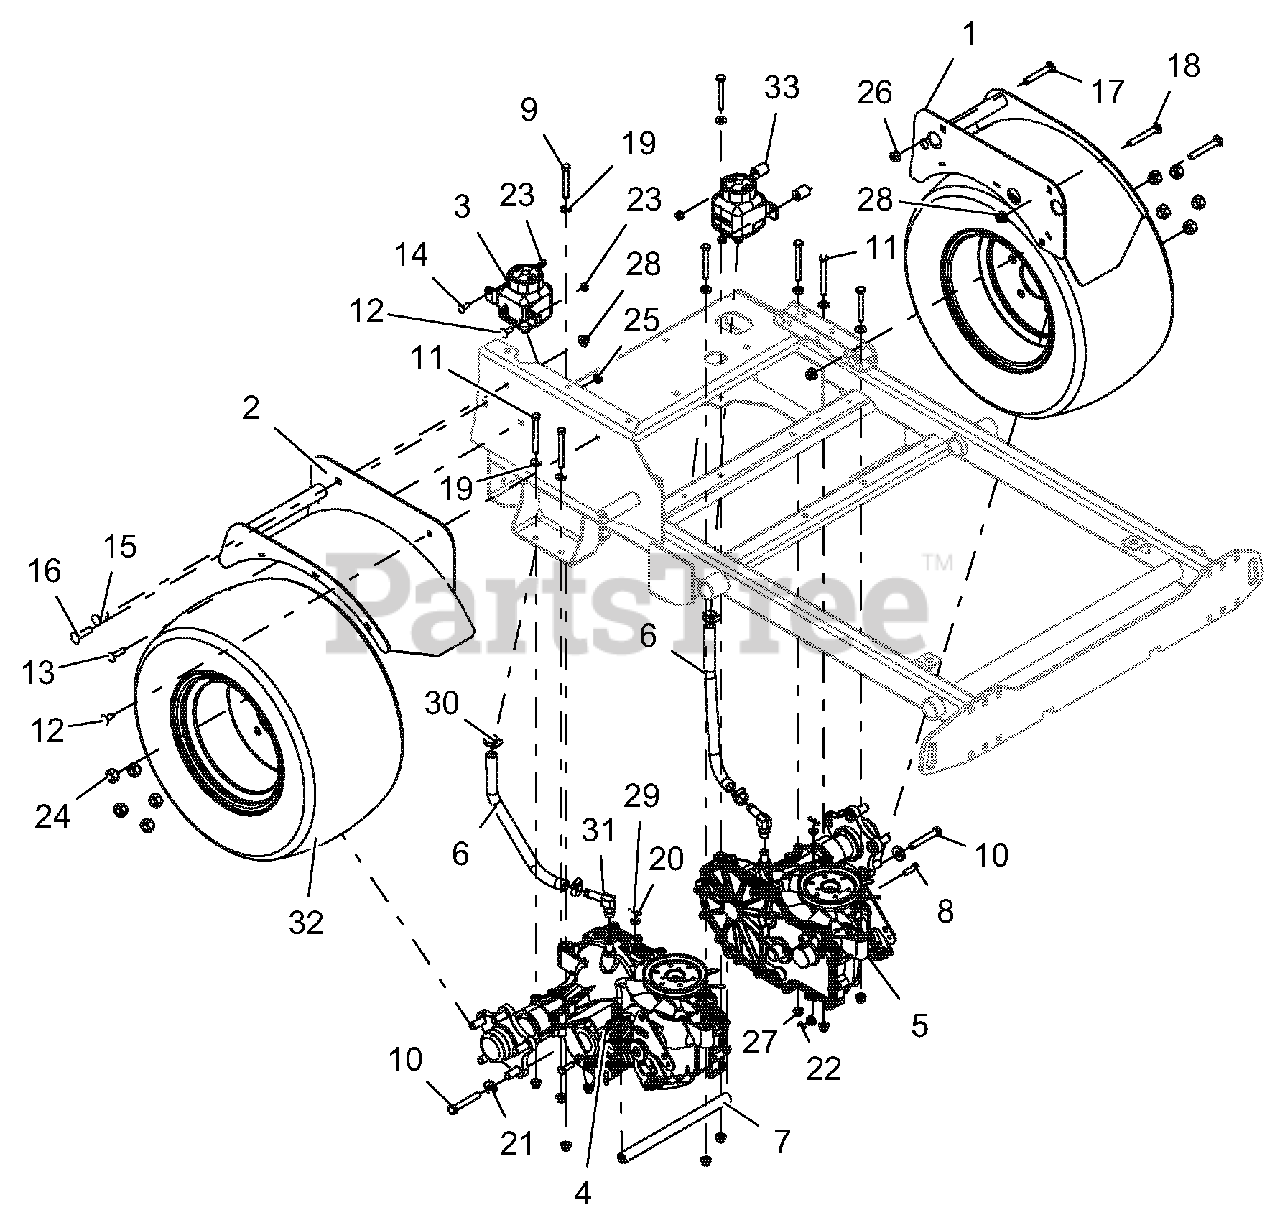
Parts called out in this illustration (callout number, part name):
1	WLDMT, LH FENDER-RED
2	WLDMT, RH FENDER-RED
3	TANK, EXPANSION ZT2800
4	TRANSAXLE, 3400, PRO-STANCE, RH
5	TRANSAXLE, 3400, PRO-STANCE, LH
6	HOSE, HYD OVERFLOW
7	SHAFT, CROSS BRACE
8	BLT-HEX .31-18X1.00 GR5 YWZC
9	BLT-HEX .31-18X2.50 GR5 YWZC
10	BLT-HEX .38-16X2.50 GR5 YWZC
11	BLT-HEX .31-18X3.00 GR5 YWZC
12	BLT-RDHDSQNK .31-18X.75 G5 YWZC
13	BLT-RDHDSQNK .31-18X1.25 G5 Y
14	BLT-RDHDSQNK .25-20X.75 G5 YWZC
15	BLT-RDHDSQNK .38-16X1.00 G5 YWZC
16	BLT-RDHDSQNK .38-16X1.50 G5 Y
17	BLT-RDHDSQNK .38-16X2.50 G5 Y
18	BLT-RDHDSQNK .38-16X2.75 G5 Y
19	WSHR-FL-STL.312X.734X.065 YWZ
20	WSHR-FL-STL.281X.62X.065 YWZC
21	WSHR-FL-STL .406X1.00X.188 YWZC
22	@NUT-LK-CTR-JAM .31-18 YWZC
23	NUT-LK-NYL-FLG .25-20 YWZC
24	NUT, LUG .500-13
25	@NUT-SPNLK-FLG .312-18 YWZC
26	NUT, LK-TOP-FLG .38-16 YWZC
27	NUT-LK-NYL-FLG .31-18 YWZC
28	NUT-LK-NYL-FLG .38-16 YWZC
29	PIN-HAIR, ENDRIES #25 YWZC
30	CLAMP, .88 DIA HOSE
31	FITTING, HYD (90 DEG)
32	ASSM TIREWHEEL, 20X10.50X.8
33	ECCENTRIC
